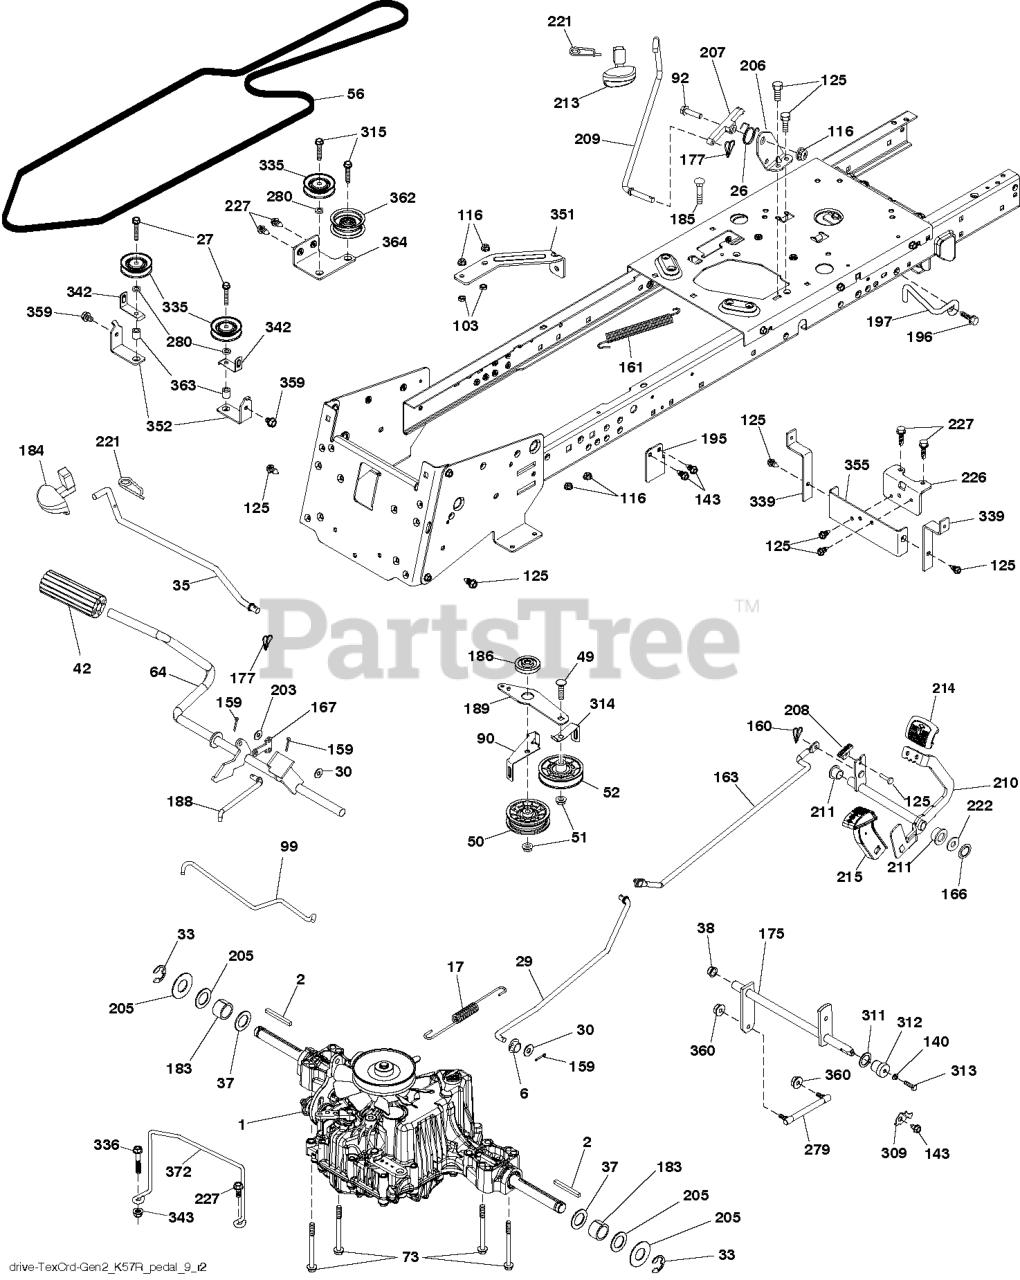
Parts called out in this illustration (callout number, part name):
2	SQUARE KEY
6	BUSHING.SNAP.NYL.BLK.
17	SPRING
26	SPRING.RETURN.CRUISE
29	ROD ROD BRAKE K46 TCRD GEN 2
37	WASHER.HARDENED
38	NYLINER SNAP 5/8" ID
42	PEDAL COVER
50	IDLER.FLAT.910.OFFSET
51	NUT LOCK FLG 3/8-16 UNC
52	IDLER.V-GROOVE.910.OFFSET
56	BELT.DRIVE.CRD.GENII.EURO.HYDR
64	SHAFT.ASM.PEDAL.BRK.CNTR
90	KEEPER KEEPER BELT CLUTCHING T
99	ROD ROD BYPASS CRD TEX GEN 2
125	SCREW
140	WASHER SPRING LOCK WASHER WITH
160	GSPW Retainers
161	SPRING, RETURN LT
166	NUT.PUSH.625
167	LATCH.BRAKE.SPRING
175	SHAFT SUBASM.SHAFT.CROSS.SHIFT
177	PIN COTTER;LOCKING;BOWTIE;1IN
183	SPACER AXLE
184	HANDLE.PARKING.BRAKE.H (BLK)
186	SPACER.RETAINER
188	LINK.CLUTCH.GROUND DRIVE.LONG
189	BELLCRANK BELLCRANK GROUNDDRI
195	BRACKET.ROD.BRAKE
196	SCREW 3/8-16X1
203	WASHER 11/32 X 11/16 X 14 GA T
206	BRACKET.MOUNT.CRUISE.LATCH
210	ROCKER.ASM.PEDAL.CONTR
211	BEARING.NYLON
213	KNOB.CONTROL.CRUSIE.HU
214	PEDAL.FORWARD.PAD.TEX
215	PEDAL.COVER.REVERSE.CRD.X428BK
221	RETAINER.SPRING.CLIP.H
222	WASHER 21/32 X 1-1/4 X 10 GA.
226	BRACKET.MOUNT.TORQUE.K46.TLT
309	PLATE FASTENING LT
311	WASHER NYL
312	HUB.TAPERED.ROUND.CRD
314	RETAINER KEEPER BELT
315	BOLT.5/16-18X1.25
335	PULLEY.V-IDLER.
339	STRAP STRAP TORQUE K46 CRD TE
342	BELT GUIDE
343	NUT HEXAGON FLANGE 5/16-18 ST
351	BRACKET BRACKET DECK SWAY
352	BRACKET BRACKET IDLER CRD TEX
355	STRAP STRAP TORQUE K46 CRD TEX
360	NUT NUT HEX CENTERLOCK 5/16-24
362	IDLER.FLAT.2.25.INCH
363	SPACER SPACER 343X63X.62
364	BRACKET BRACKET IDLER CRD TEX
372	KEEPER.BELT.CRD2.K46.2.BOLT.
